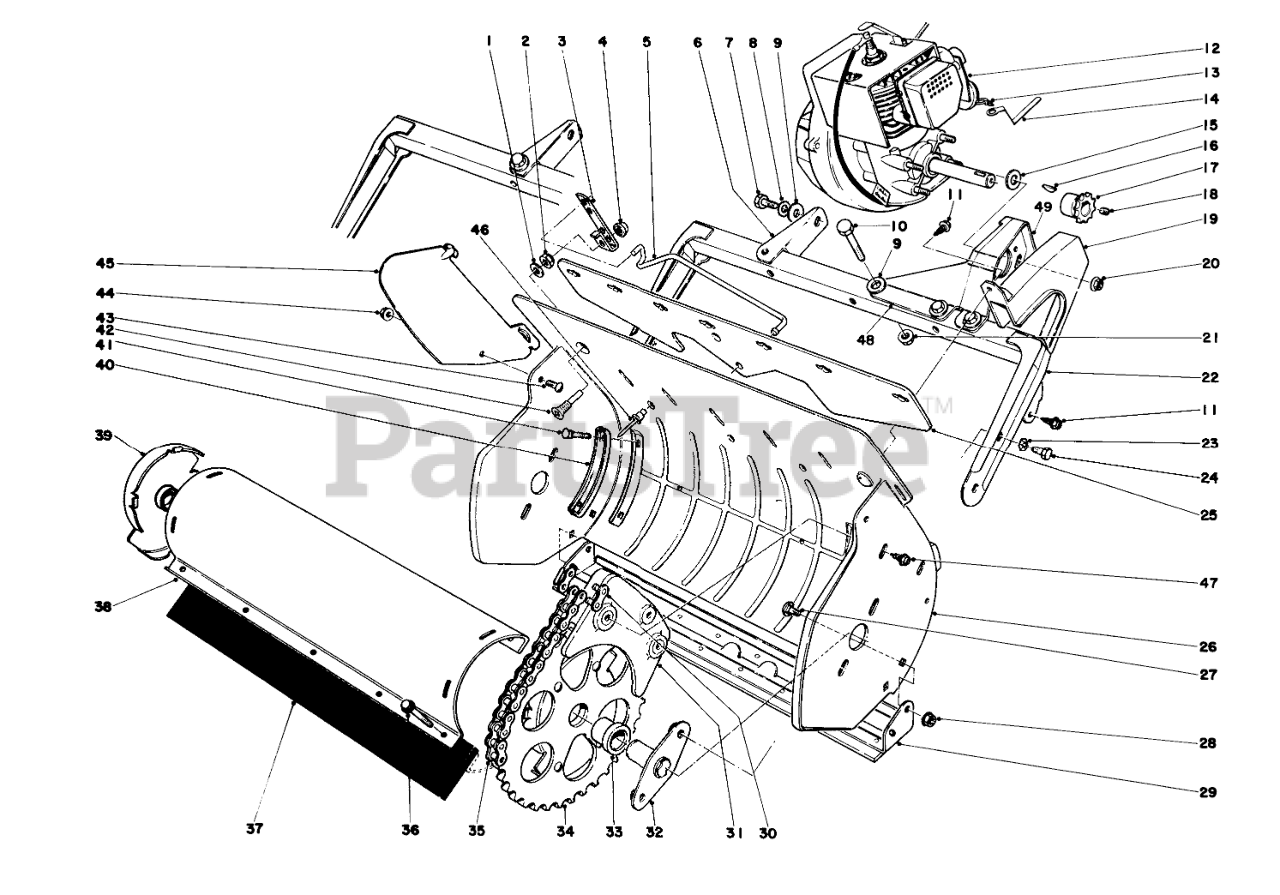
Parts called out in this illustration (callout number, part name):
1	WASHER-FLAT
2	NUT-LOCK, NI
3	Bracket-Vane Adj.
4	Hair Pin Cotter
5	Linkage Vane Adj.
6	Bracket
7	SCREW-HH
8	WASHER-LOCK/EXT
9	WASHER-FLAT
10	SCREW-HH
11	SCREW-HWHTF
12	Engine
13	Cotter Pin
14	Strap-Choke
15	WASHER-PLAIN
17	SPROCKET
18	SCREW-SET, HSH
19	Chain Guard
20	NUT-HHF
21	Nut
22	Frame Assembly
23	Washer
24	Screw
25	Mount-Vane
25	Mount Vane
26	Housing
27	SCREW-CARRIAGE
28	NUT-KEPS
29	Skid Riveted
29	Skid
30	LINK-CONNECTING, NO. 35
31	Stripper
32	Rotor Shaft
33	ROTOR BUSHING
34	End Cap Assembly LH (Incl. Ref. #33)
35	CHAIN
36	Screw
37	BLADE ROTOR
37	ROTOR BLADE
38	Shell Rotor
38	ROTOR SHELL
39	End Cap Assty (Incl. Ref. #33)
40	Handle Plate
41	SCREW-CARR
42	Screw
43	SCREW-PTH
44	NUT-LOCK, FLANGE
45	Vane
46	RIVET
47	Screw
48	Bracket Engine
49	Bracket Engine
